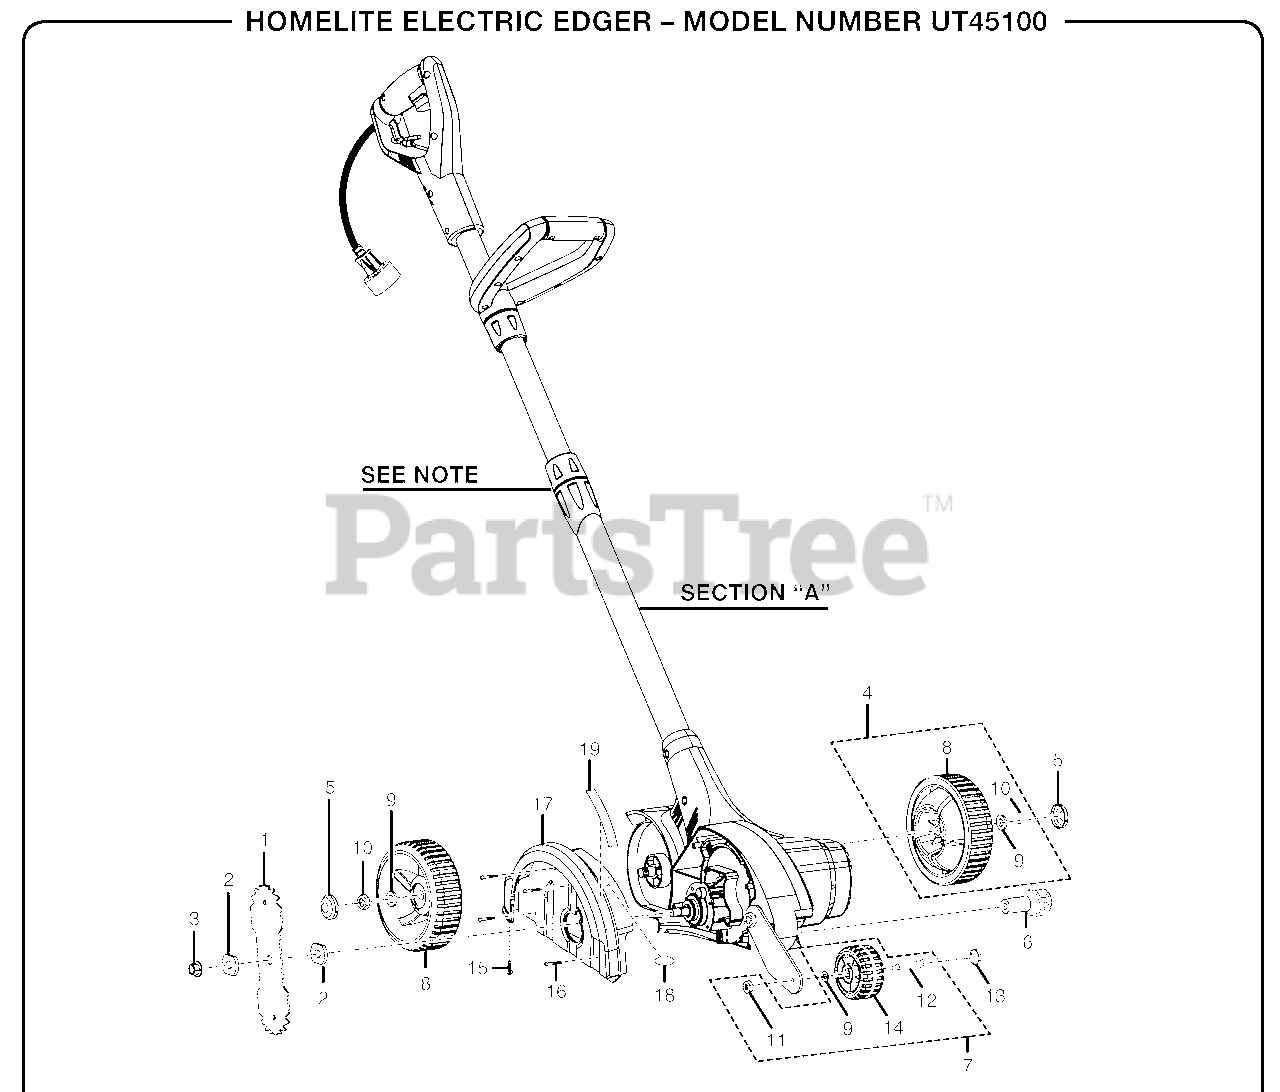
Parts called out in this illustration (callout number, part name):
2	Blade Washer
3	Blade Nut
4	Rear Wheel Set
5	Rear Wheel Cap
6	Depth Adjustment Knob
7	Front Wheel Set
9	Washer
10	Lock Nut
11	Lock Nut
12	Front Wheel Axle
13	Front Wheel Cap
14	Front Wheel
15	Screw
16	Screw
17	Guard Assembly
18	Warning Label
19	Cutting Edge Label
